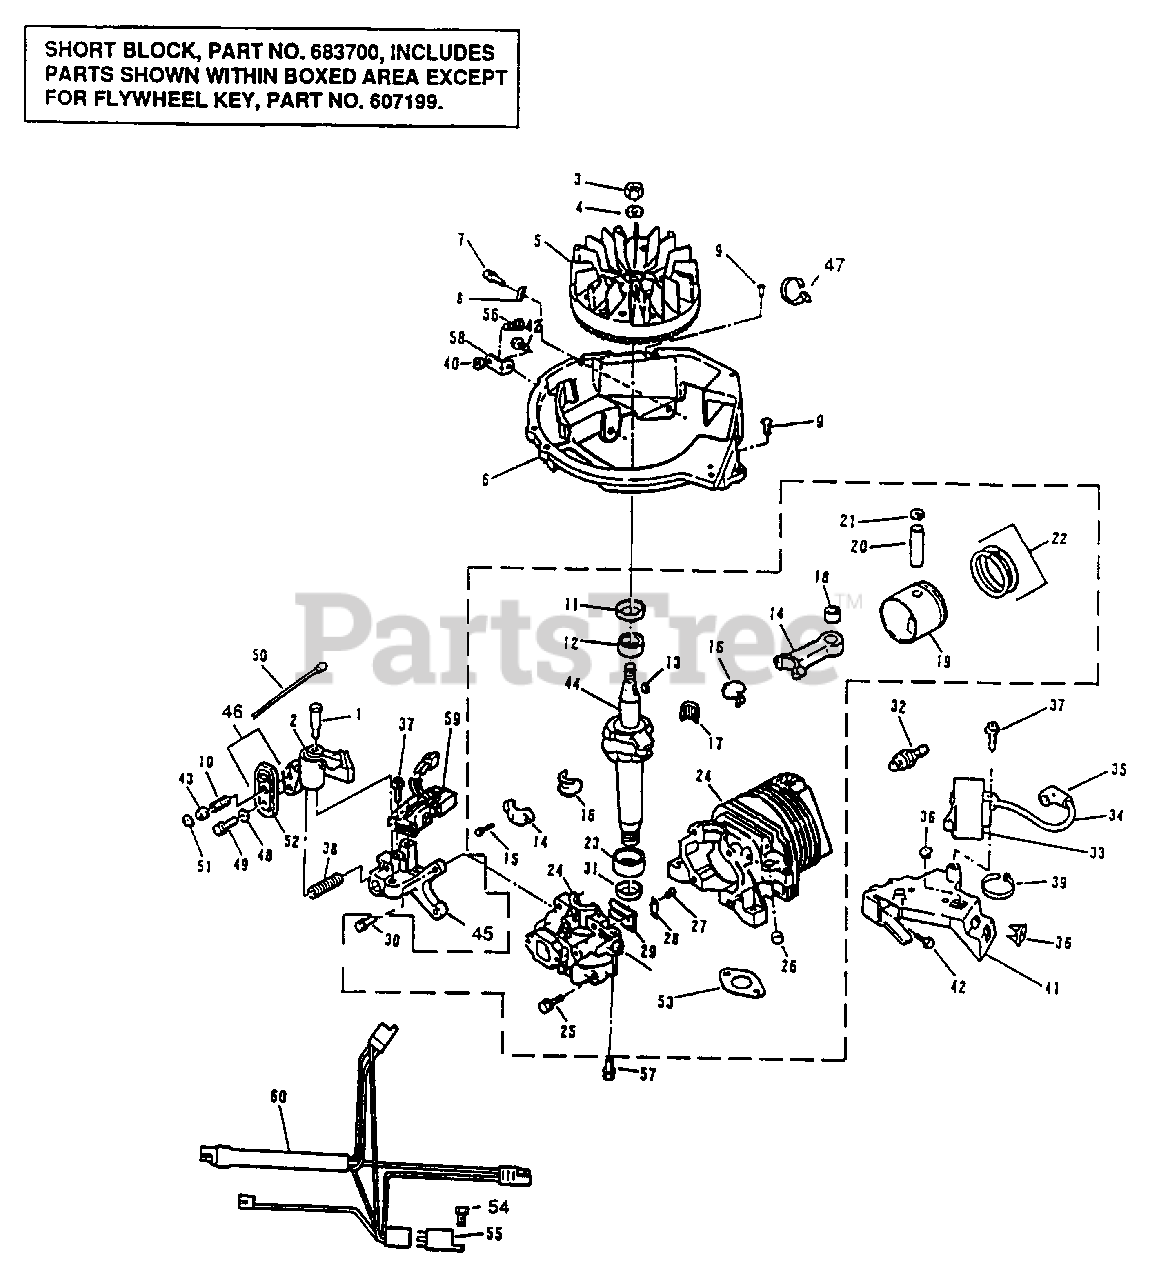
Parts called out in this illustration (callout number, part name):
1	Bolt-Shoulder
2	Brake Assembly
3	Nut-Flywheel
4	Lockwasher
5	Flywheel Assembly
6	Base-Shroud
7	Screw
8	Clip-J
9	Screw
10	Spring-Cable Return
11	Oil Seal-Upper
12	Bearing-Main-Upper
13	Key-Flywheel
14	Connecting Rod Assy (Inc. 15-18)
15	Screw-Cap
16	Liner Split
17	Needle Bearing Set
18	Bearing Assembly
19	Piston & Ring Set (Inc. 20-22)
20	Wrist Pin
21	Retaining Ring
22	Ring Set
23	Bearing-Main-Lower
24	Cylinder & Crankcase Cover Asy. (Inc. 25-30)
25	Screw-Cover To Crankcase
26	Plug
27	Screw-Reed To C'case Cover
28	Plate-Reed Hold Down
29	Reed
30	Screw-Brake Mounting Bkt.
31	Oil Seal-Lower
32	Spark Plug
33	C.D. Ignition Module & Lead Asy (Inc. 34-35)
34	High Tension Lead & Cvr (Inc. 35)
35	Cover & Terminal Assembly
36	Grommet
37	Screw-C.D. Mounting
38	Spring-Brake
39	Tie Strap
40	Nut
41	Bracket-C.D. Mounting
42	Screw
43	Actuator-Brake Lever
44	Crankshaft
45	Bracket
46	Switch Assembly (Inc. 47-52)
47	Tie Strap
48	Washer
49	Screw
50	Lead Assembly
51	Retainer
52	Case Assembly-Only
53	Exhaust Gasket
54	Screw
55	Relay
56	Bolt
57	Set Screw-Starter Assembly
58	Brace-Alternator Bracket
59	Alternator Assembly
60	Wire Harness Assembly
